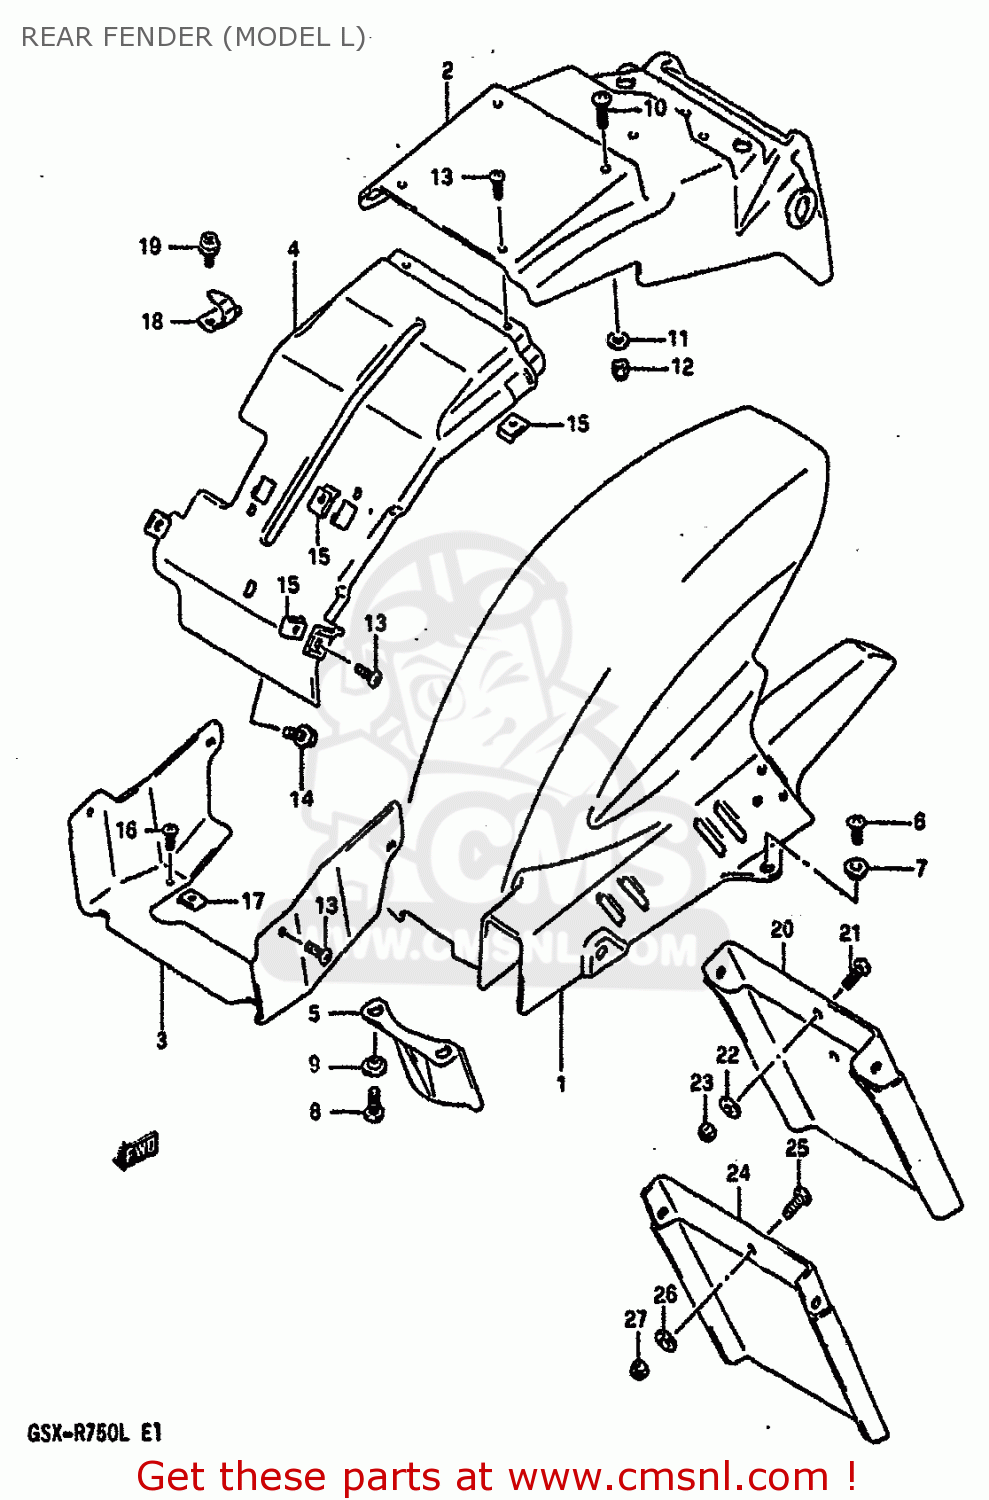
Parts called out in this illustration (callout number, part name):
1	FENDER,RR LWR
2	FENDER,REAR UPPER
3	FENDER,REAR
4	FENDER,RR UPR FR NO.2
5	GUARD,RR UNIT MUD
6	SCREW
7	WASHER
8	SCREW
9	WASHER,LOCK
10	SCREW
11	WASHER
12	NUT
13	SCREW, FRONT & REAR
14	BOLT
15	NUT,HEADLAMP HOUSING,UPPER
16	SCREW, FRONT & REAR
17	NUT,HEADLAMP HOUSING,UPPER
18	HOLDER,HELMET
19	BOLT
20	EXTENSION, REAR FENDER
21	SCREW
22	WASHER
23	NUT
24	MUD GUARD,REAR FENDER
25	SCREW
26	WASHER
27	NUT
